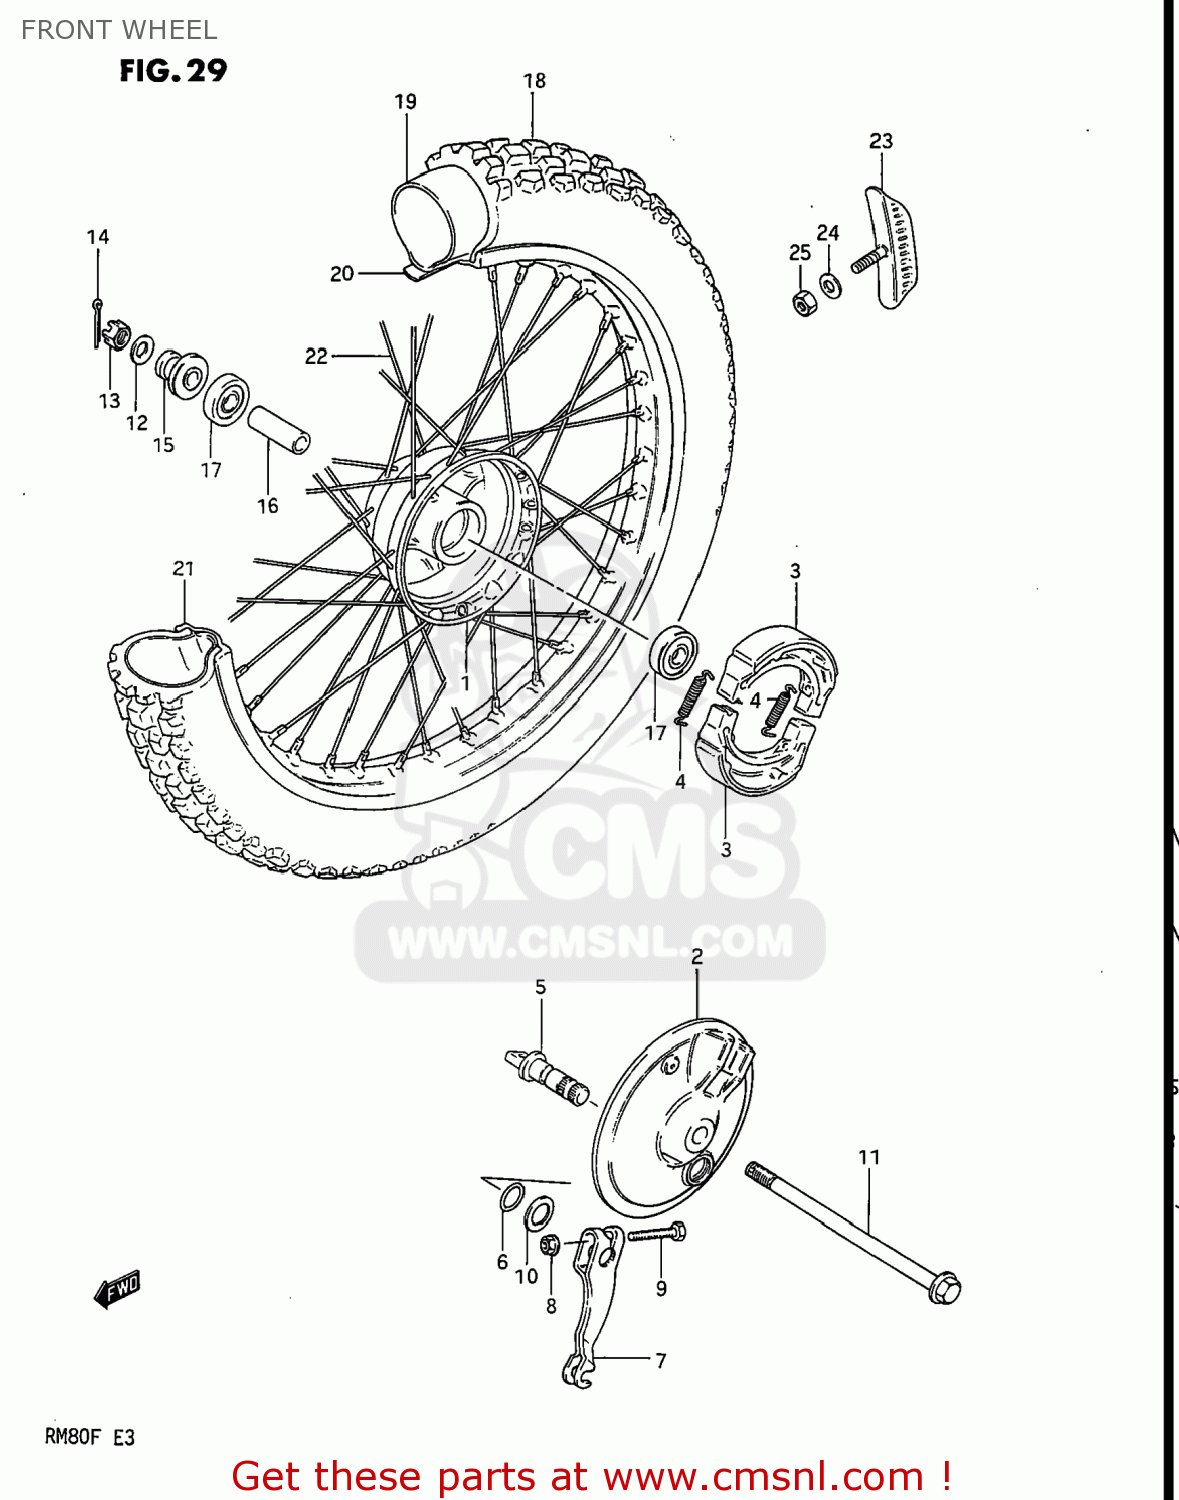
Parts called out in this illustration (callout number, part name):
1	HUB,FRONT
2	PANEL,FRONT HUB
3	SHOE,BRAKE (MCA)
4	SPRING(L:35.8)
5	CAM,BRAKE
6	O RING(D:2.5,ID:11.4)
7	LEVER,FRONT BRAKE CAM
8	NUT
9	BOLT
10	WASHER(12.5X20X1)
11	AXLE,FRONT
12	WASHER
13	NUT
14	PIN 20X20
15	SPACER,FRONT AXLE,RIGHT
16	SPACER (10.4X15X48)
17	BEARING
18	TIRE,FRONT
19	TUBE,INNER
20	PROTECTOR,WHEEL,INNER
21	RIM,FRONT WHEEL
22	SPOKE SET,FRONT
23	STOPPER,BEAD
24	WASHER
25	NUT
